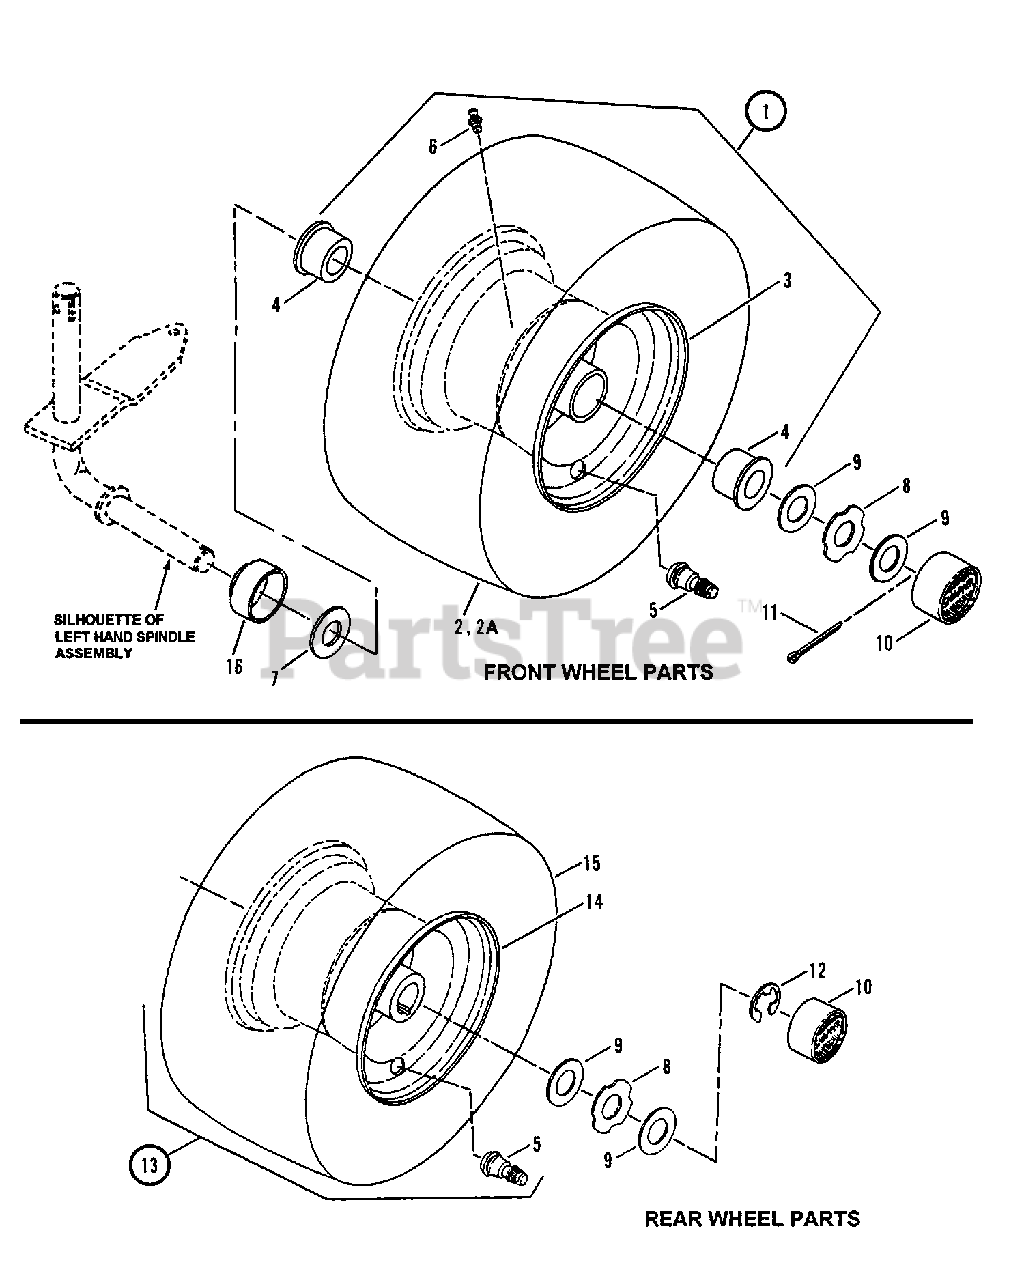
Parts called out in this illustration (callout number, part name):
1	ASSEMBLY, Front Tire & Rim (Incl. items 2, 3, 4, 5 & 6)
1	ASSEMBLY, Front Tire & Rim (Incl. items 2A, 3, 4, 5 & 6)
2	TIRE, 13 x 5.00 K500- Tread Kenda
2A	TIRE, 15 x 6.00-6 K500 Tread Kenda
3	RIM, 6.00 x 3.50, Grey
4	BEARING, Wheel PM
5	VALVE STEM, Air (Snap-In)
6	FITTING, Lube 1/4-28 Tapered Thread
7	WASHER, 5/32 x 25/32" I.D. x 1-1/2" O.D. Flat
8	WASHER, Hub-Cap Retaining
9	WASHER, 3/4 x 1-5/16 x 1/16"
10	HUB CAP
11	PIN, 5/32 x 1" Cotter
12	RING, 3/4" External Retaining
13	ASSEMBLY, Rear Tire & Rim (Includes items 5, 14 & 15)
14	RIM, 8 x 7.00 Keyed Hub, Grey
15	TIRE, 18 x 8.50-8 K500 Tread, Kenda
16	DUST CAP
